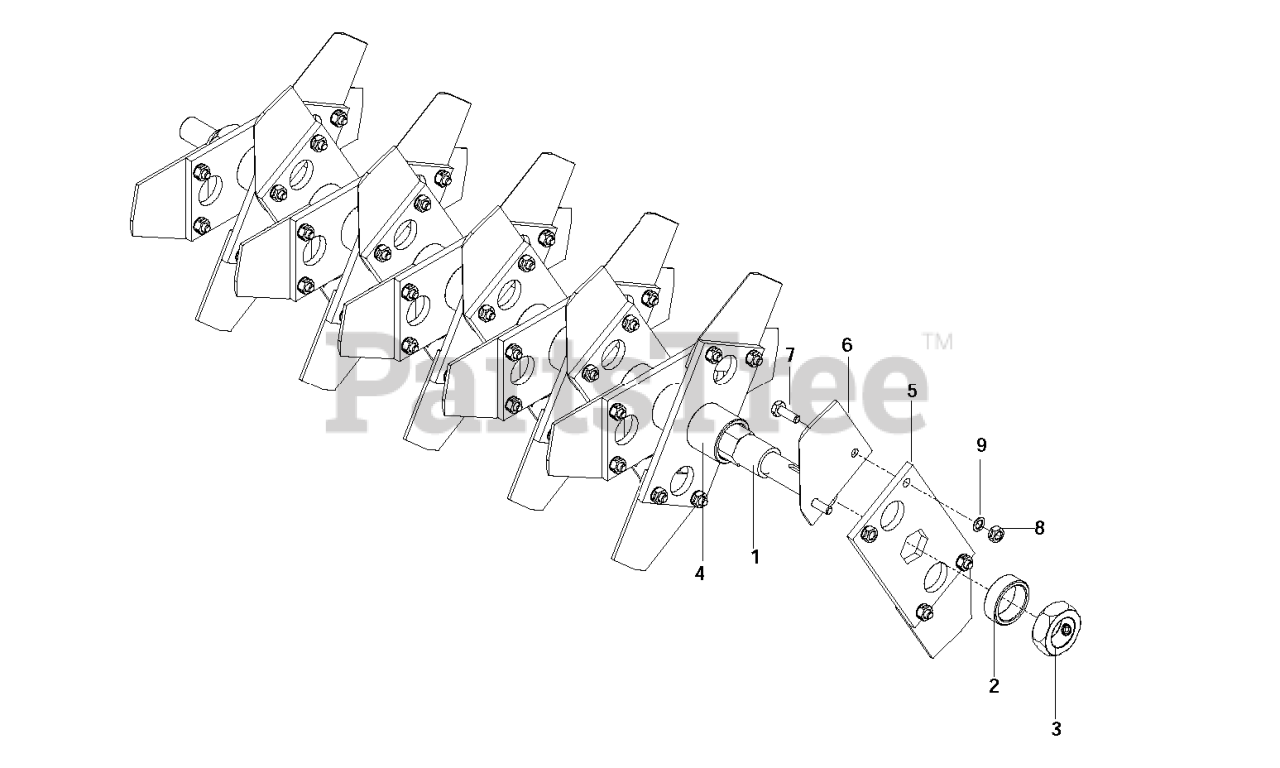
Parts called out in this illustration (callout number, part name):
1	22" DELTA REEL (COMPLETE)
2	END SPACER
3	JAM NUT W/SET SCREW
4	SPACER - LONG
5	BLADE MOUNTING PLATE
6	DELTA BLADE
7	HEX SCREW 1/4X.75
8	NUT 1/4C CENTER LOCK
9	TH CABLE AR# 441L-632-10
